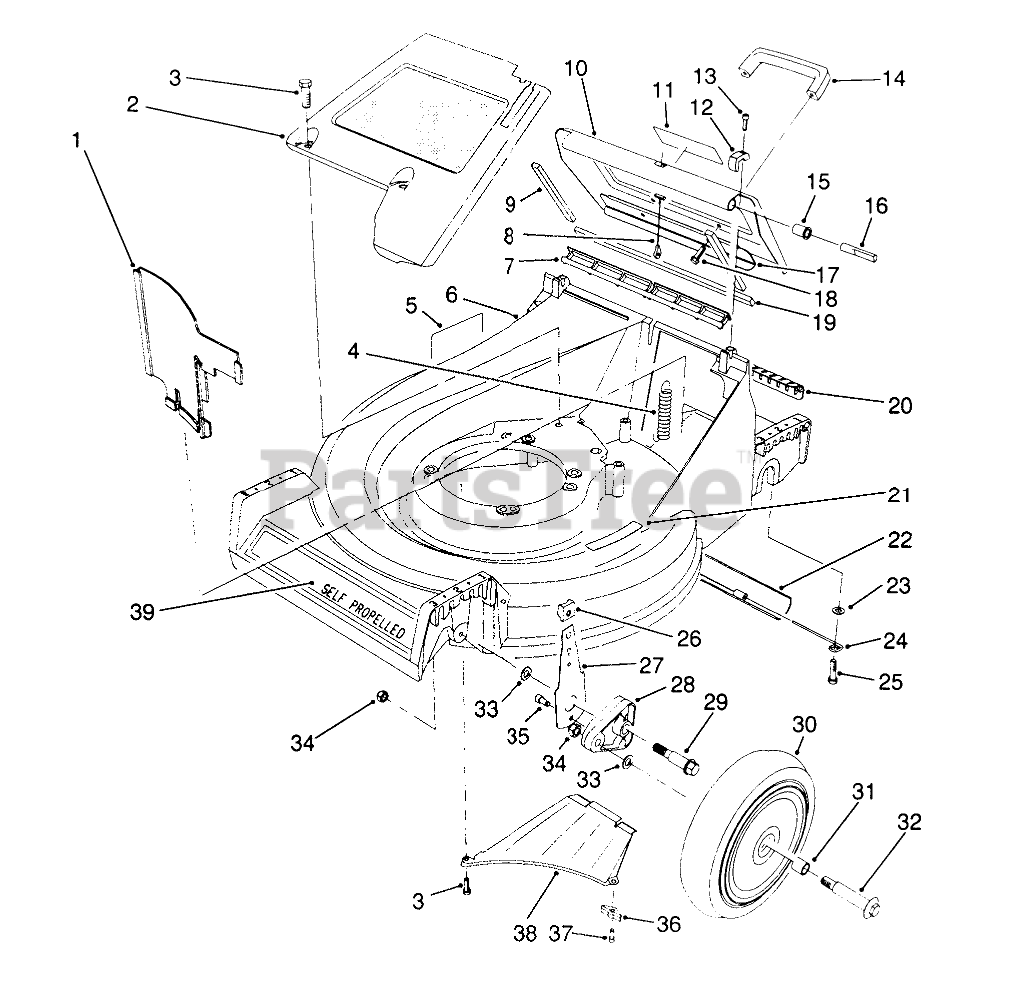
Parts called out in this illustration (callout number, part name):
1	PANEL-VERTICAL
2	PaneI-Screen
3	SCREW-HWHTF
4	EXTENSION-SPRING
5	DECAL-DANGER
6	21" Housing Assembly (Incl. Ref. #5, & 21)
7	DOOR SEAL
8	DOOR CABLE
9	DOOR SIDE SEAL
10	Door-Discharge (Incl. Ref. #9, 11, 17 & 19)
11	DECAL - DANGER
12	HINGE CLAMP
13	SCREW-HSH
14	HANDLE-DOOR
15	DOOR BUSHING
16	HINGE PIN
17	DOOR - BRACE
18	SCREW-HWH
19	DOOR END SEAL
20	ACCESS COVER
21	DECAL - STEP PAD INT'L
22	TRAILING SHIELD
23	WASHER-PLAIN
24	SHIELD HANGER
25	SCREW-SHOULDER
26	KNOB-ARM
27	FRONT SPRING ARM ASM
28	ARM-PIVOT, FRONT
29	BOLT-SHOULDER
30	Wheel & Tire Assembly (Incl. Ref. #29)
31	BUSHING
32	WHEEL BOLT
33	WASHER
34	Nut
35	SCREW-HSH, THREAD FORMING
36	Bracket-Discharge
37	SCREW-HWHTF
38	Ramp Discharge
39	DECAL - 53 CM
